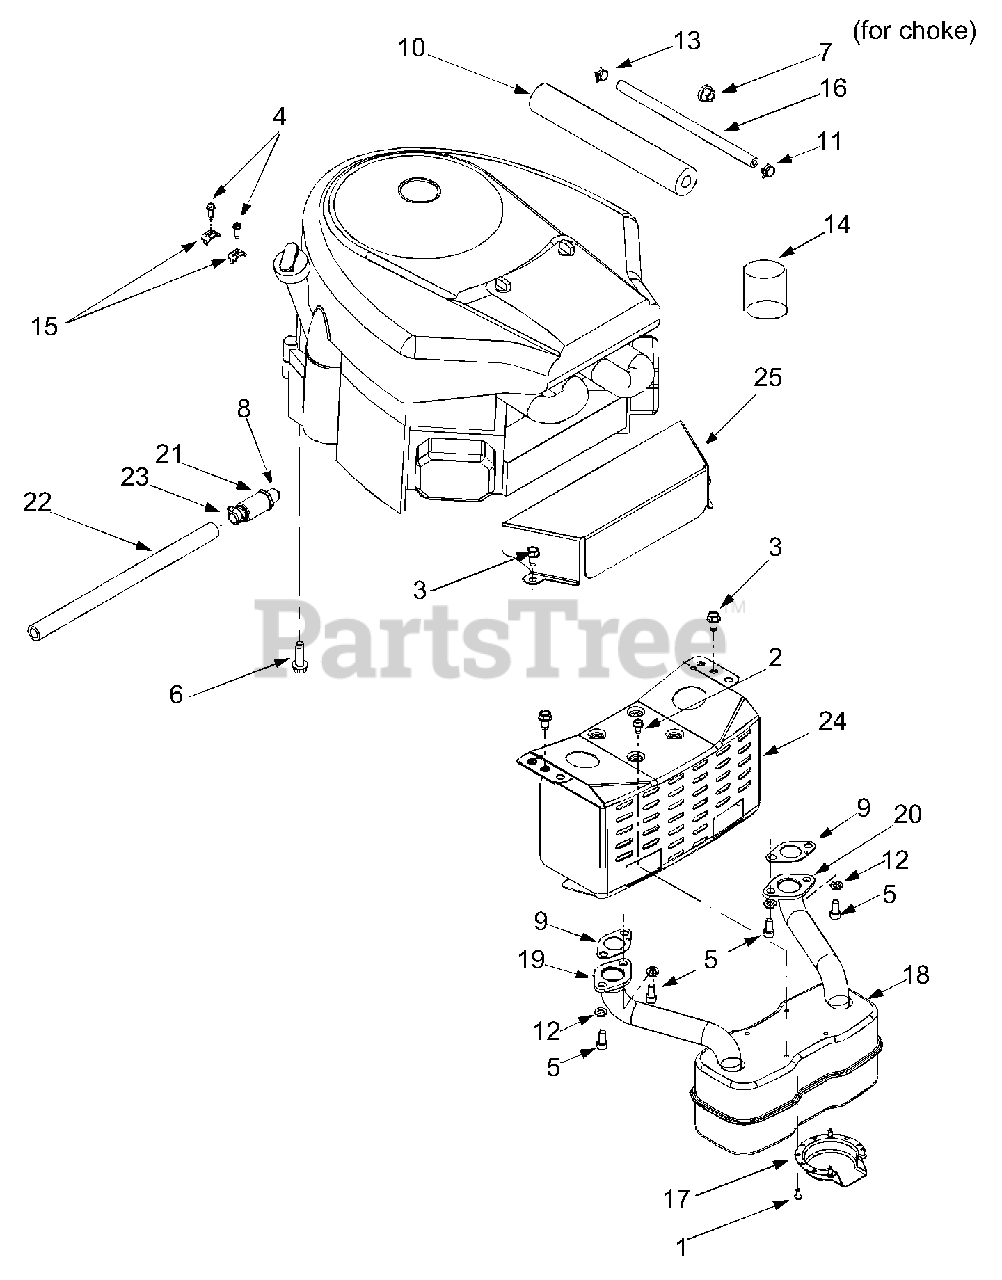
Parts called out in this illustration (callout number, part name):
1	Self-tapping Screw, #8-18 x .50"
2	Self-tapping Screw, 1/4-20 x .50"
3	AB Screw 5/16-12 x 0.75"
4	Screw, #10-32 x .625
5	Socket Cap Screw, 5/16-18 x .625
6	TT Screw 3/8-16 x 1.250"
7	Hex Nut 3/8-16
8	Sealant
9	Exhaust Gasket
10	Foam
11	Hose Clamp
12	Lock Washer
13	Flat Washer
15	Casing Clamp
16	Fuel Line Hose
17	Deflector: Muffler
18	Muffler: Dual Inlet
19	Exhaust Pipe RH
20	Exhaust Pipe LH
21	Oil Drain
22	Hose: Oil Drain Extension
23	Oil Drain Cap
25	Heat Shield
